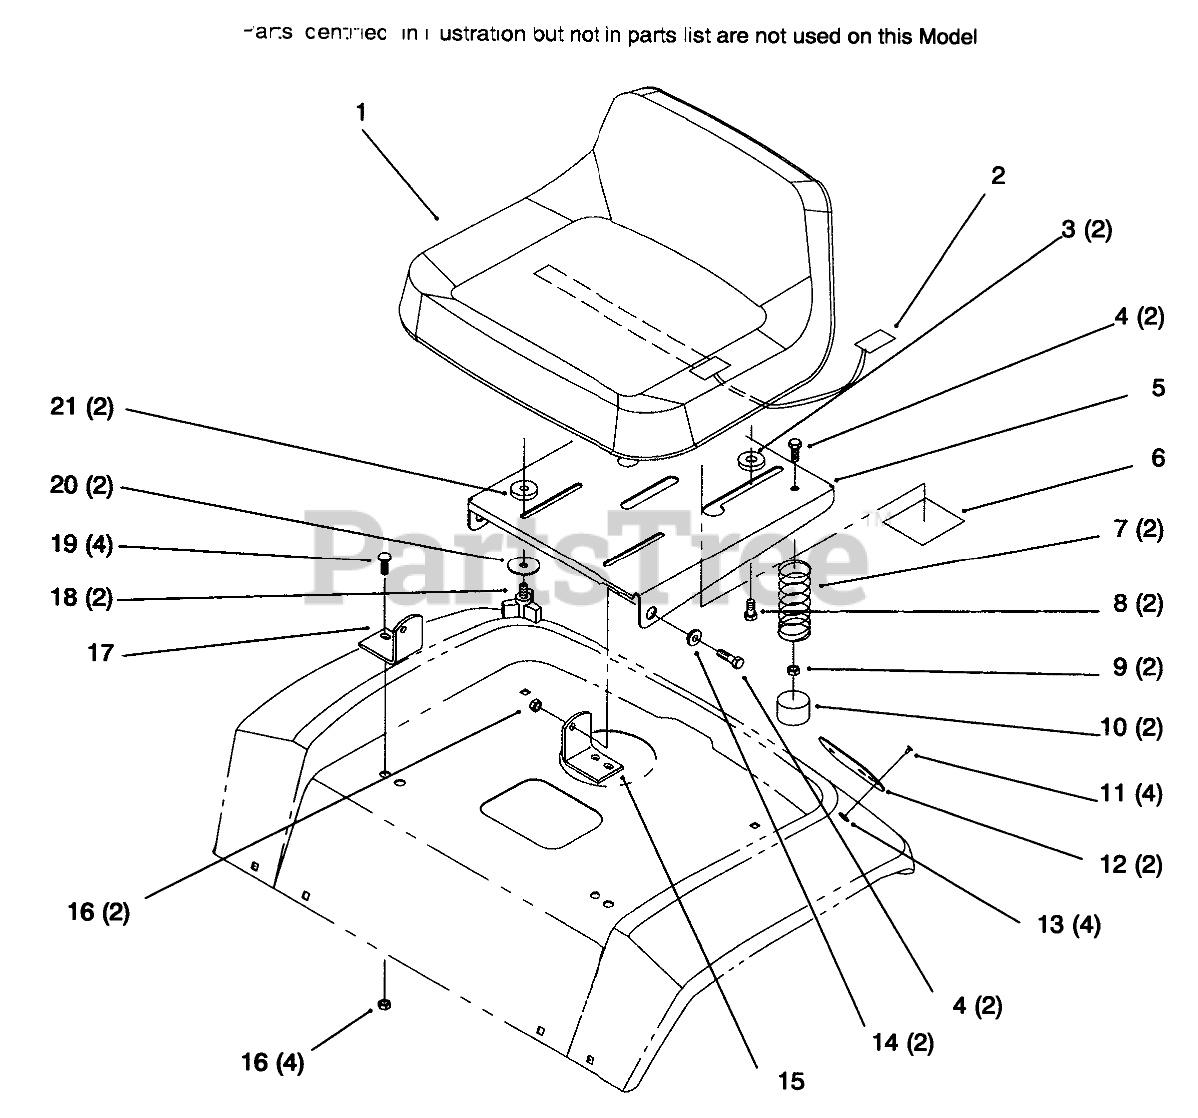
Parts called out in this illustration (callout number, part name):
1	SEAT-V-511
1:1	TRIM - SEAT
2	SWITCH-SEAT
3	SPACER-NYLON
4	SCREW-HH
5	SUPPORT - SEAT (BLACK)
6	Decal-Noise (Only On: 72104)
7	SPRING-COMPRESSION
8	BOLT-SHOULDER
9	NUT-LOCK, NI
10	CAP-PROTECTOR
11	RIVET-BLIND
12	REFLECTOR-STICK ON
13	WASHER-PLAIN
14	BUSHING
15	BRACKET-PIVOT, LH
16	NUT-LOCK, NI
17	BRACKET-PIVOT, RH
19	BOLT-CARR
20	WASHER
21	SPACER-NYLON
